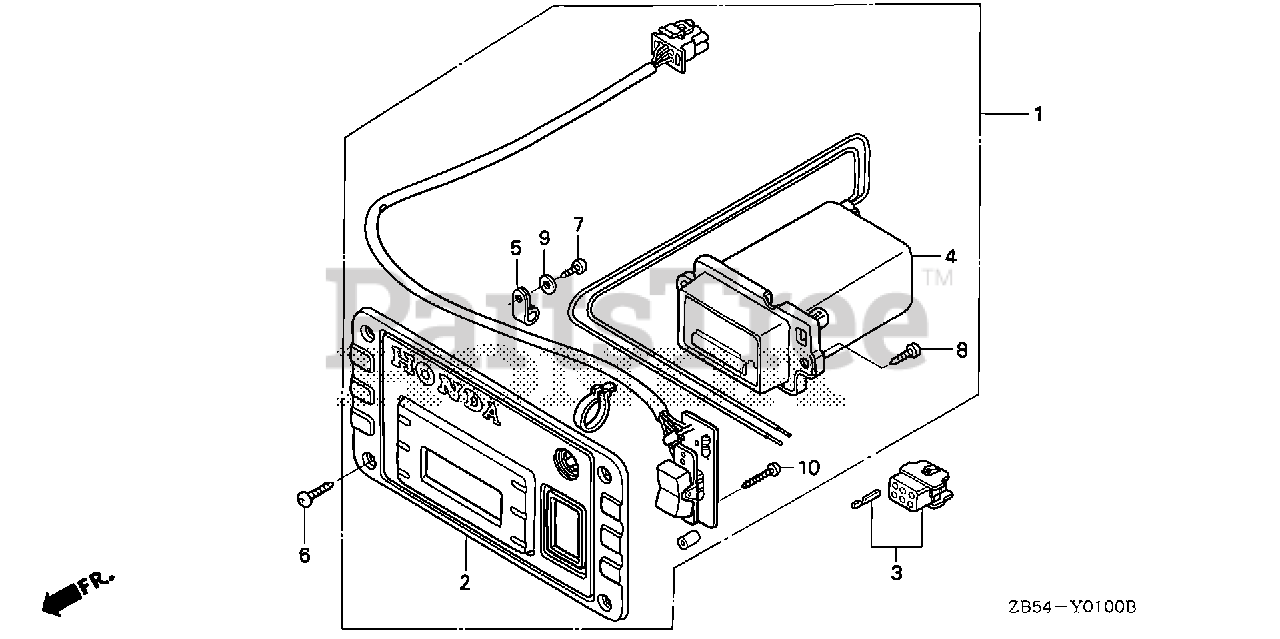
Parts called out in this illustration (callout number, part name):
1	PANEL ASSY., REMOTE CONTROL
2	PANEL, FR. REMOTE
3	CONNECTOR ASSY., PLUG
4	METER ASSY., HOUR
5	CLIP (7.5MM)
6	SCREW, TAPPING (3X10)
7	SCREW, TAPPING (4X12)
8	SCREW, TAPPING (5X16)
9	WASHER, PLAIN (4MM)
10	SCREW, TAPPING (3X20)
